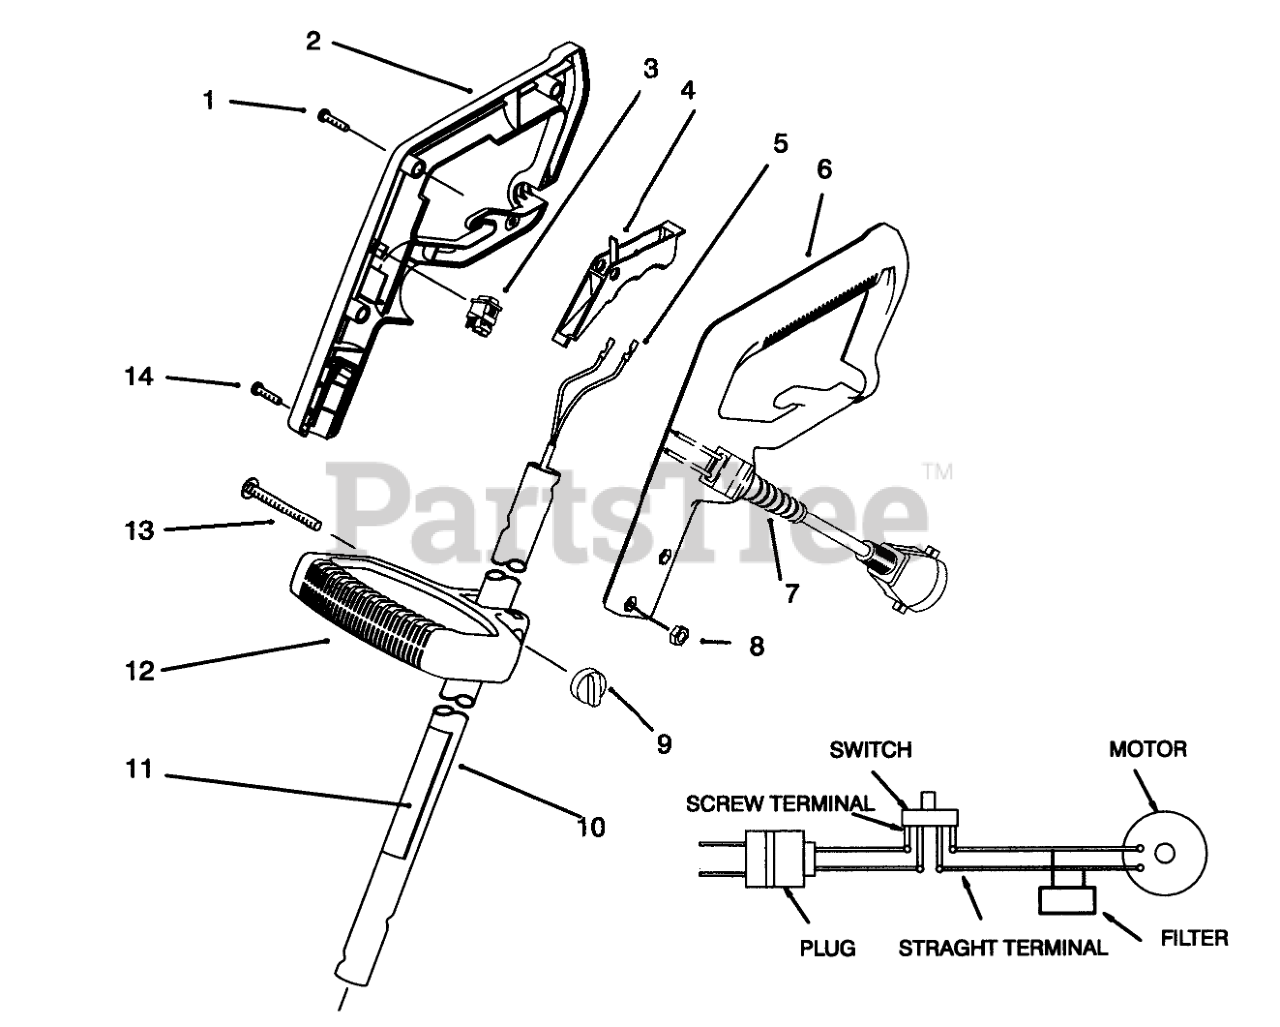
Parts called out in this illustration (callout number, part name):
1	Screw
2	HAND GRIP RH
3	SWITCH - 230V
4	TRIGGER
5	HARNESS - WIRE
6	HAND GRIP LH
7	CORD - POWER
8	NUT-HEX
9	KNOB, VFL/FFL
10	Tube Assembly (Incl. Ref. #11)
11	Decal-Safety
12	MID HANDLE
13	SCREW-CARR
14	SCREW-PPH
